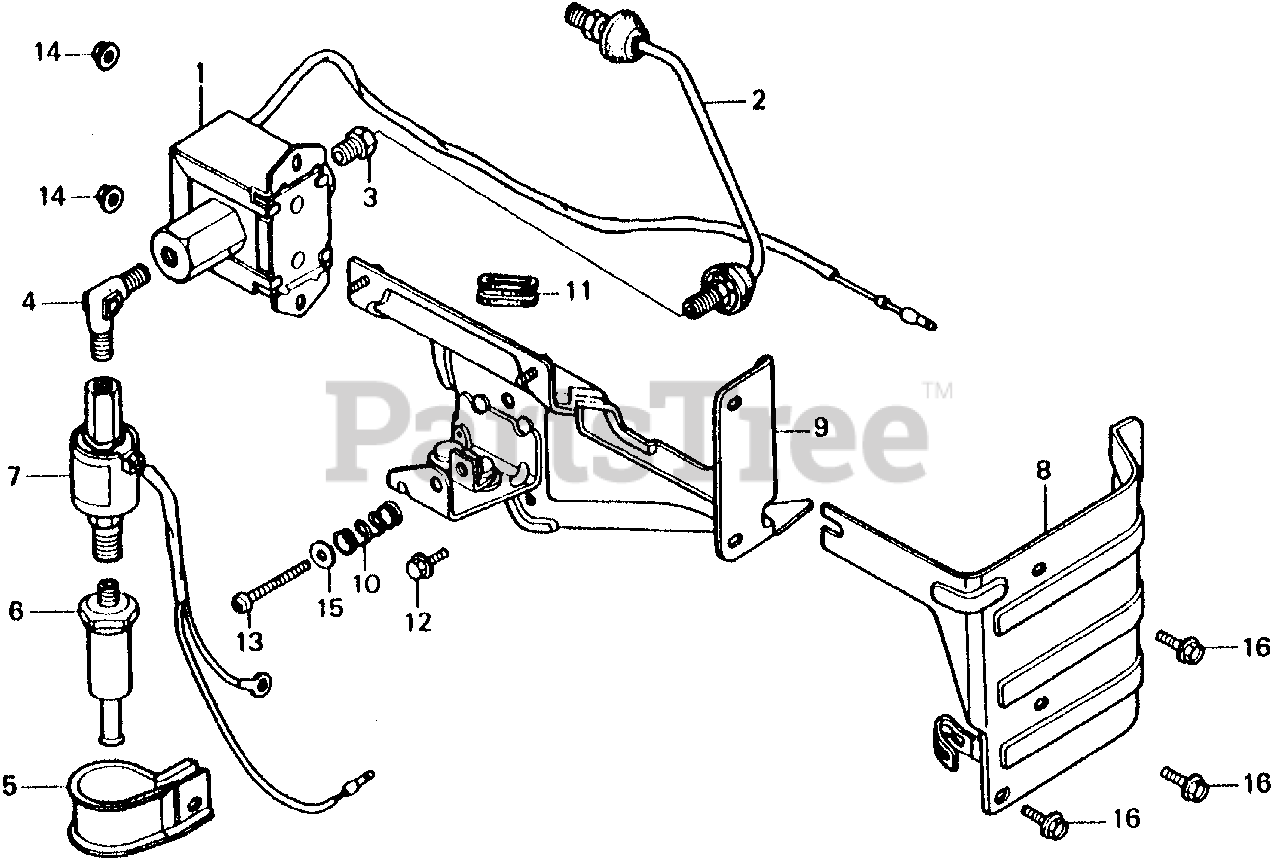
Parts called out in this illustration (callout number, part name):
1	PUMP ASSY., FUEL (NOT AVAILABLE)
1	PUMP ASSY., FUEL
2	PIPE, FUEL
3	NUT, JOINT
4	JOINT, FUEL ELBOW
5	HOLDER, FUEL CUT
6	FILTER, FUEL LINE
7	PETCOCK, FUEL CUT
8	SUPPORT, AIR CLEANER HOUSING
9	STAY, AIR CLEANER HOUSING
10	SPRING, THROTTLE ADJUSTING
11	GROMMET, WIRE
12	BOLT, FLANGE (6X12) (CT200)
13	SCREW, PAN (6X40)
14	NUT, CAP (6MM)
15	WASHER, PLAIN (6MM)
16	BOLT, FLANGE (6X12)
